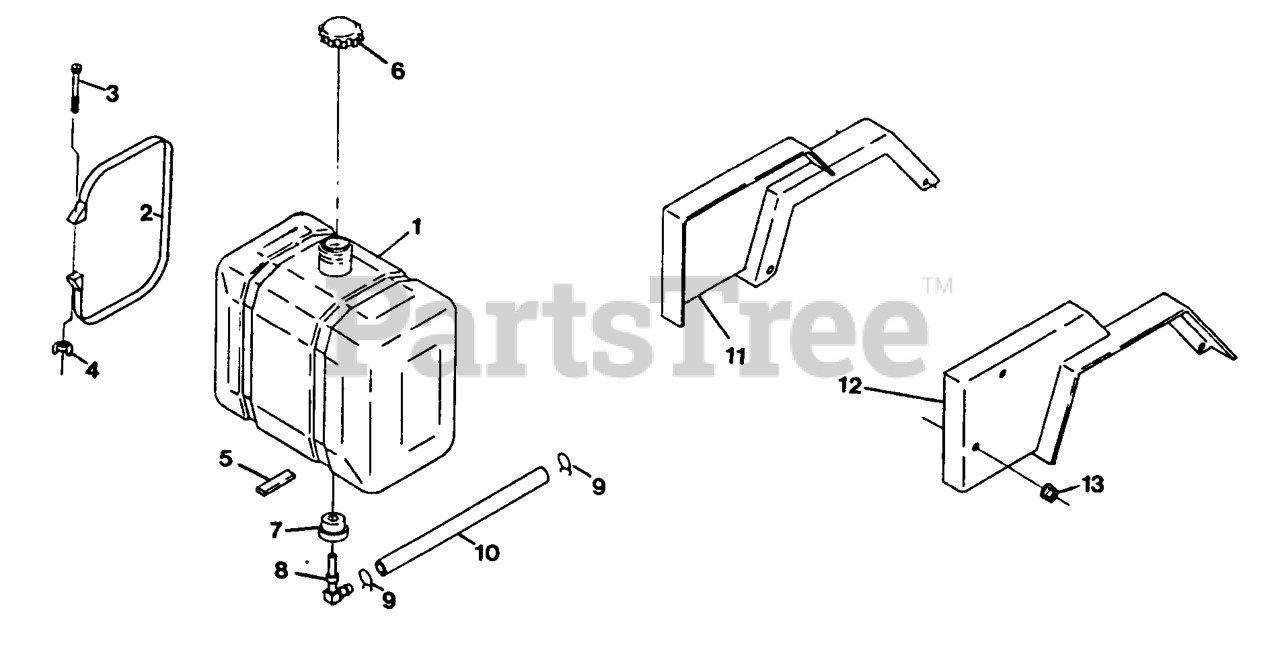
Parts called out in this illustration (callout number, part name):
3	SCRW,MACH CRPH
4	WINGNUT
5	PAD,PLASTIC TANK
6	CAP-FUEL
8	ELBOW-TANK, FUEL
10	HOSE-LINE, FUEL
